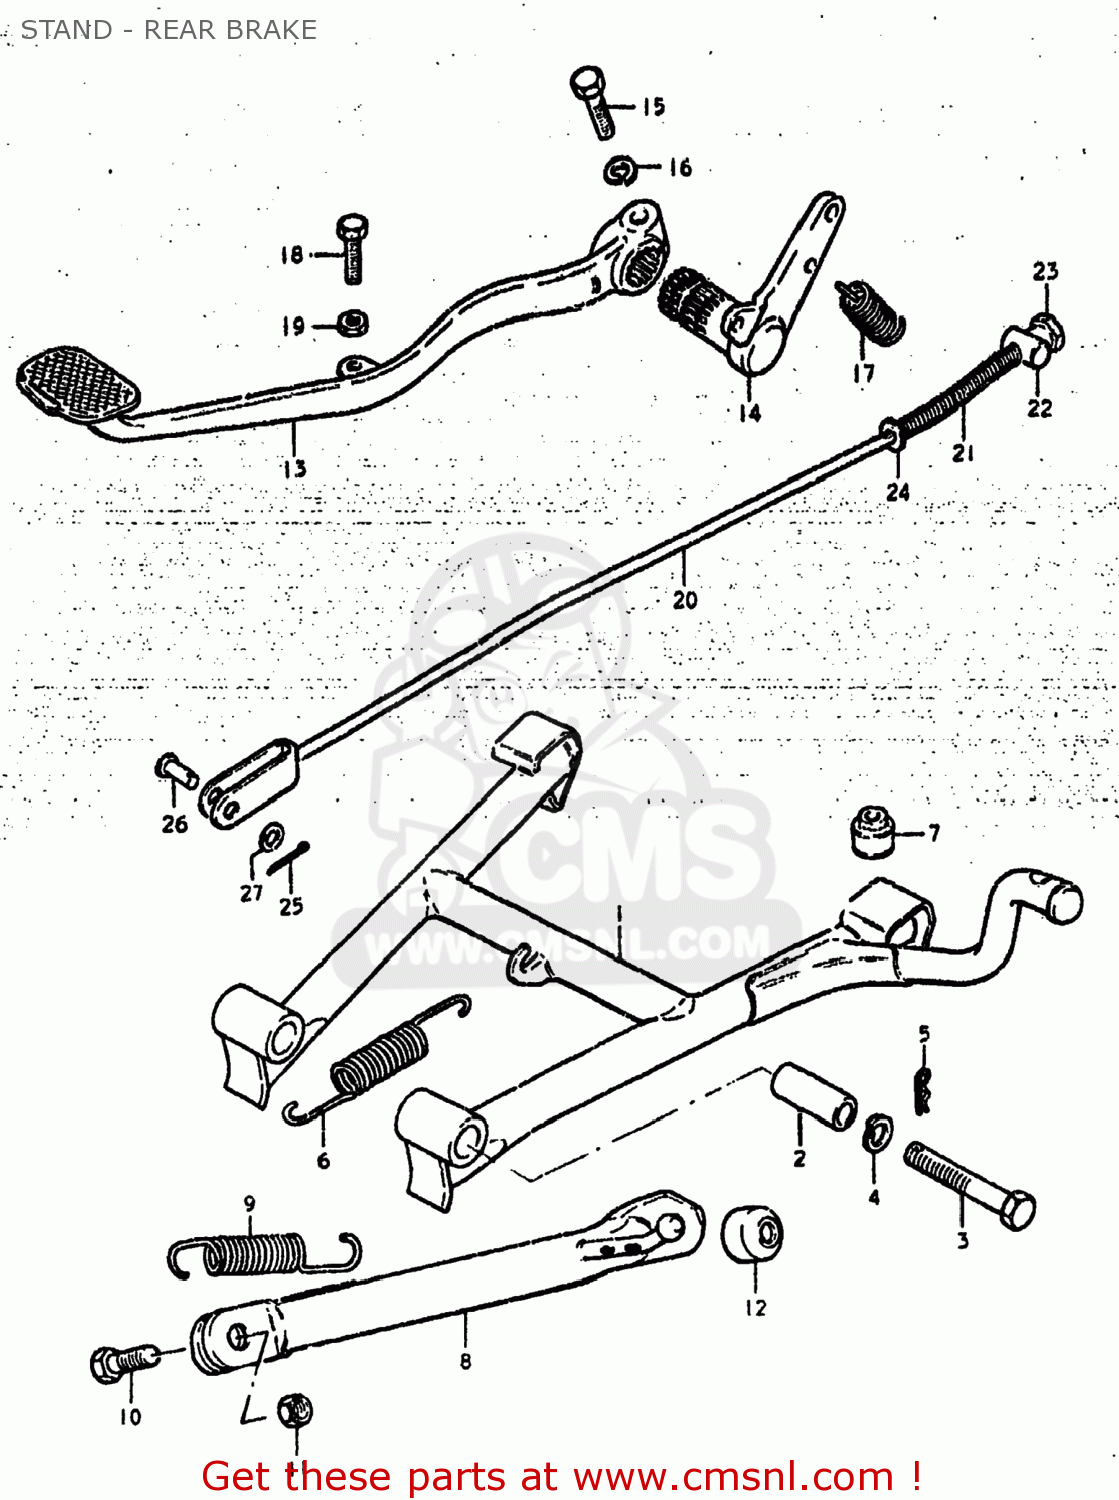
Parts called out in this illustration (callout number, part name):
1	STAND,CENTER
2	SPACER(10X16X38.8)
3	BOLT
4	LOCK WASHER
5	CLIP
6	SPRING
7	CUSHION
8	STAND,SIDE
9	SPRING
10	BOLT(10X30)
11	NUT
12	CUSHION
13	PEDAL,BRAKE
14	ARM,BRAKE PEDAL ROD
15	BOLT
16	LOCK WASHER
17	SPRING
18	BOLT
19	NUT
20	ROD ASSEMBLY,REAR BRAKE
21	SPRING
22	PIN
23	NUT
24	WASHER
25	PIN 20X20
26	PIN(L:13.5)
27	WASHER
